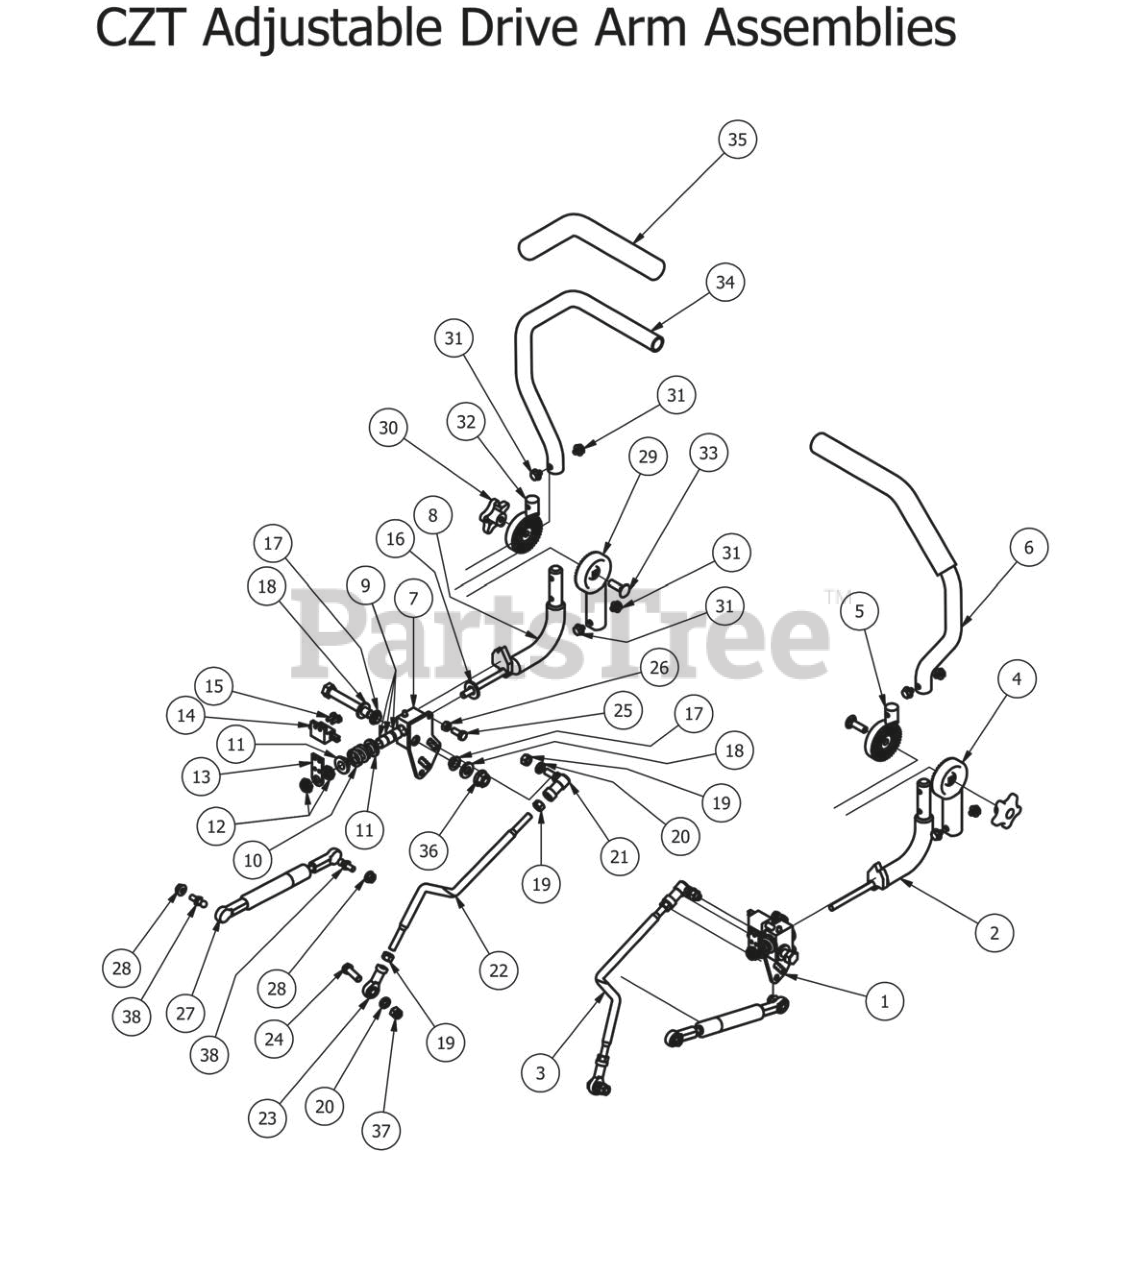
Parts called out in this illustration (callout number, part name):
1	2013 Drive Lever Housing (Right)
2	Steering Arm Elbow - Right
3	Push Rod for ZT/CZT - Right
4	Lower Adjuster - Steering Arm- Right
5	Upper Adjust Steering Arm- Right
6	Upper Tube-Adjustable Steering
7	2013 Drive Lever Housing (Left)
8	Steering Arm Elbow - Left
9	.507 ID Nylon Bushing
10	Drive Lever Spring
11	.515 ID Nylon Shoulder Washer
12	1/2" Nylcock Nut (1/2 Jam)
13	MZ Switch Bracket
14	Safety Switch
15	12-24x 1/2 HWH Bolt
16	.505 Nylon Spacer
17	Bushing for 2012 Drive Arms
18	.505x1x.125 Oil Impregnated washer
19	3/8" Fine Threaded Jam Nut
20	3/8" Lock Washer
21	3/8-24 Quick Release Ball Joint
22	Push Rod for ZT/CZT - Left
23	Spherical Rod End - Outlaw
24	3/8" x 1 1/4" Hex Bolt
25	5/16" x 3/4" Hex Bolt
27	Steering Damper For Outlaw
28	5/16" Flange Nut
29	Lower Adjuster - Steering Arm- Left
30	Black Knob for Adjustable Steering Arm
31	5/16-18 1/2 HWH Bolt-Steering
32	Upper adjuster-Steering Arm- Left
33	3/8" x 1 1/4" Carriage Bolt
34	Upper Tube-Adjustable Steering
35	Black Steering Grip
36	1/2-13 Hex Flange (GR.G) ZC
37	3/8 Nylock Nut
38	10mm Damper Ball Stud-Steering
